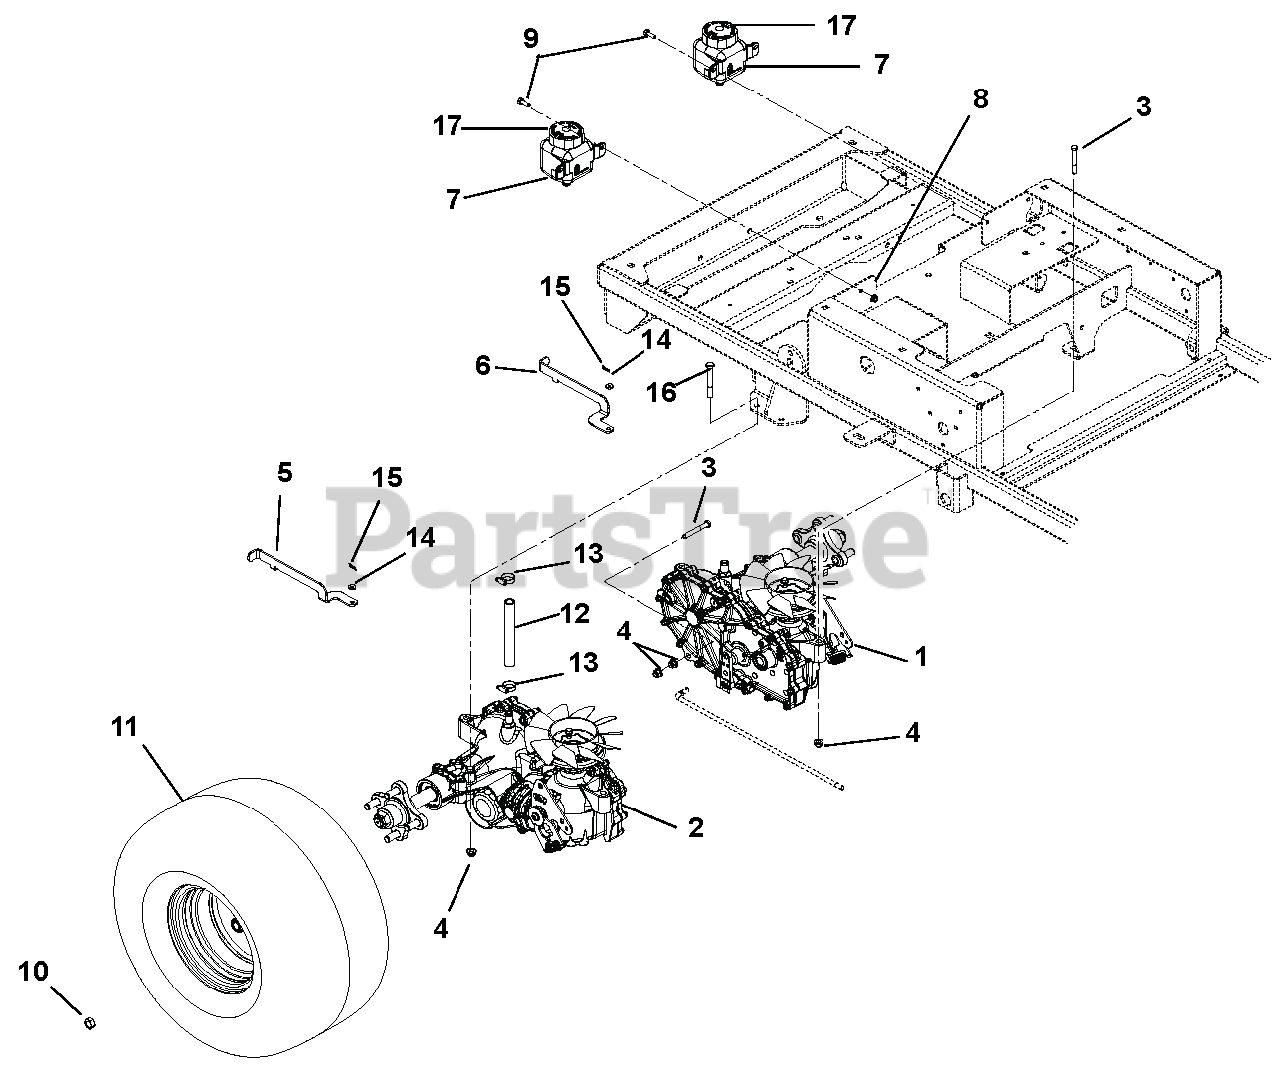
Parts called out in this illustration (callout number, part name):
1	TRANSAXLE, ZT2800 LH
2	TRANSAXLE, ZT2800 RH
3	@BLT-HEX .31-18X2.25 GR5 YWZC
4	@NUT-LK-NYL-FLG .31-18 YWZC
5	DUMP VALVE, RH
6	DUMP VALVE, LH
7	TANK, EXPANSION
8	@NUT-LK-TOP-FLG .25-20 YWZC
9	@BLT-HEX .25-20X.75 GR5 YWZC
10	WHEEL NUT .500-20 YZ
11	TIRE/WHEEL ASSY, 20X10.0-8 CTR
12	HOSE, OIL RESERVOIR
13	CLAMP,.88 DIA. HOSE
14	WSHR-FL-STL .265X.50X.087YWZC
15	PIN-HAIR INT .06X.18X.77
16	@BLT-HEX .31-18X2.75 GR5 YWZC
17	CAP, HYDRO RESERVOIR REPLAC.
